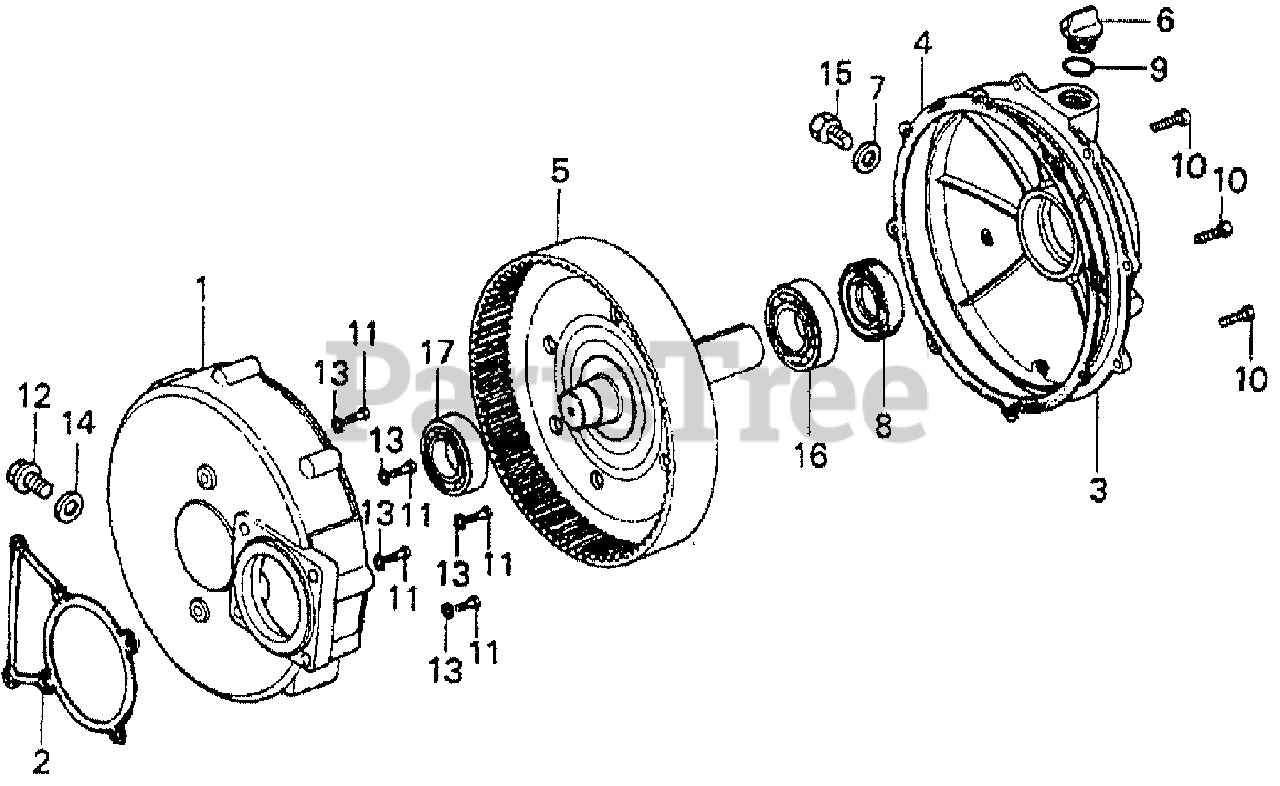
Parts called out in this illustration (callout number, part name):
1	CASE, REDUCTION
2	GASKET, REDUCTION CASE (NOT AVAILABLE)
3	COVER, REDUCTION
4	GASKET, REDUCTION COVER
5	SHAFT, P.T.O.
7	WASHER A (6MM)
8	OIL SEAL (PJ30507)
9	O-RING (16MM)
10	BOLT, HEX. (6X20)
11	BOLT, HEX. (8X32)
12	BOLT, DRAIN PLUG (12MM)
13	WASHER, PLAIN (8MM)
14	WASHER, DRAIN PLUG (12MM)
15	BOLT, FLANGE (6X10)
16	BEARING, RADIAL BALL (6205)
17	BEARING, RADIAL BALL (6206)
